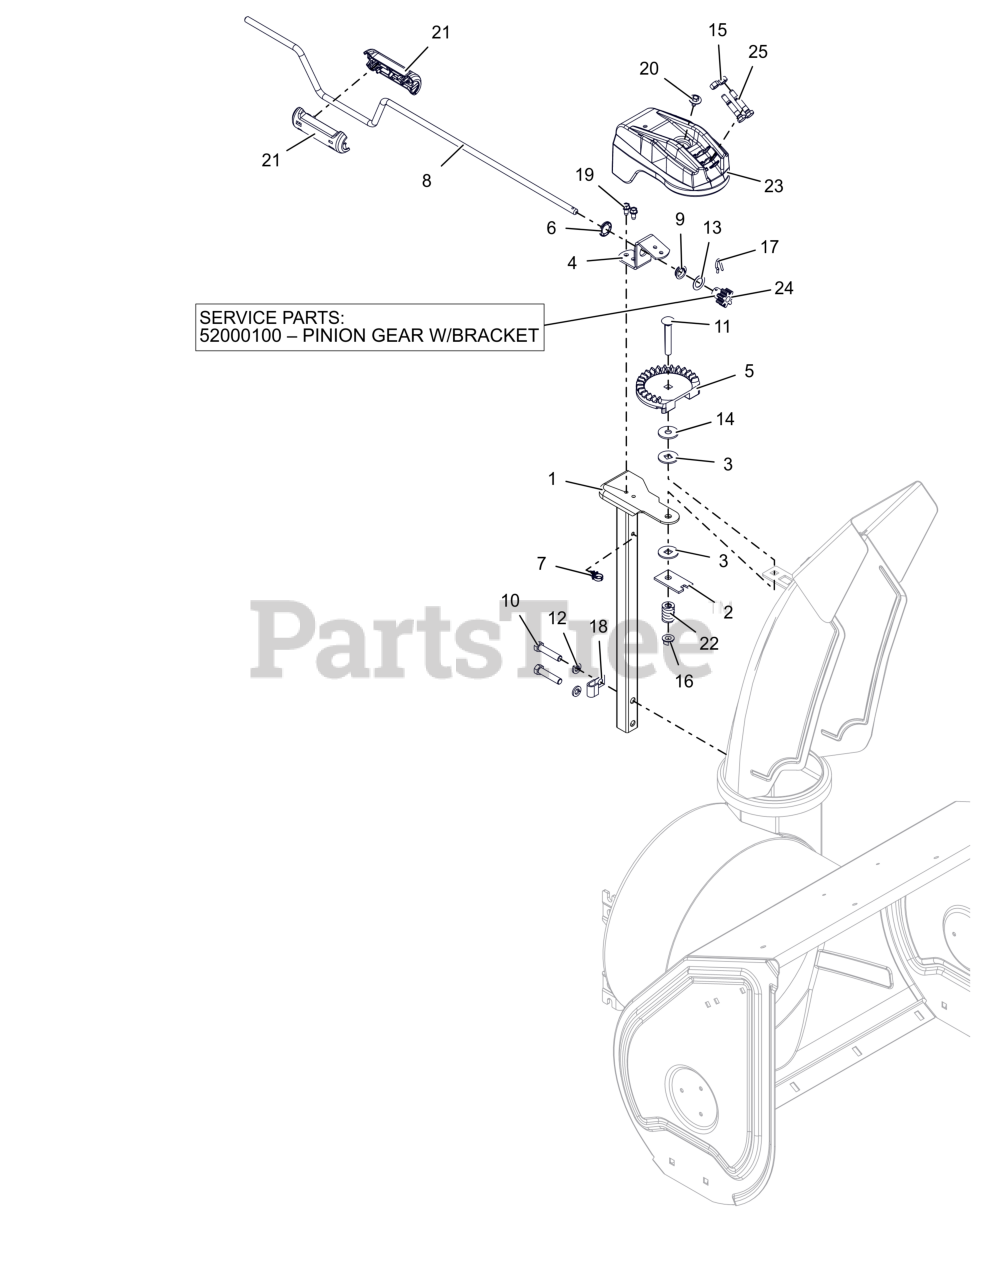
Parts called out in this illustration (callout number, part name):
1	PEDESTAL, CHUTE - CRANK
2	PLATE, FRICTION
3	FRICTION WASHER
4	BRACKET, PINION GEAR
5	CHUTE GEAR
6	PUSHNUT .625
7	CLIP, CABLE GUIDE
8	ROD, CHUTE CRANK
9	BUSHING, POLYLINER-.63 SNAPIN
10	BLT, HEX .38-16X1.75 G5 ZCC
11	BLT,RHSN .38-16X2.50 G5 ZCC
12	WSHR,LK-REG .375X.094 ZCC
13	WSHR-THRST .625 X 1.0 X .03
14	WSHR FL STL .406X1.25X.10ZC120
15	NUT,LK-CTR .31-18 GA ZCC
16	NUT-LK-CTR-FLG .375-16 GF ZCC
17	PIN, SPRING CLIP
18	J-CLAMP
19	SCR-TAP .25-20X.50 HWH ZCC
20	SCR, TAP .25-20X.50 LG HWH ZCC
21	KNOB- CHUTE CRANK
22	SG-COMP .187X.56X1.62
23	COVER, MOUNT - ICE DRILL
24	PINION, GEAR CHUTE
25	SHEAR BOLT SERVICE ASSEMBLY (INCLUDES NUT)
